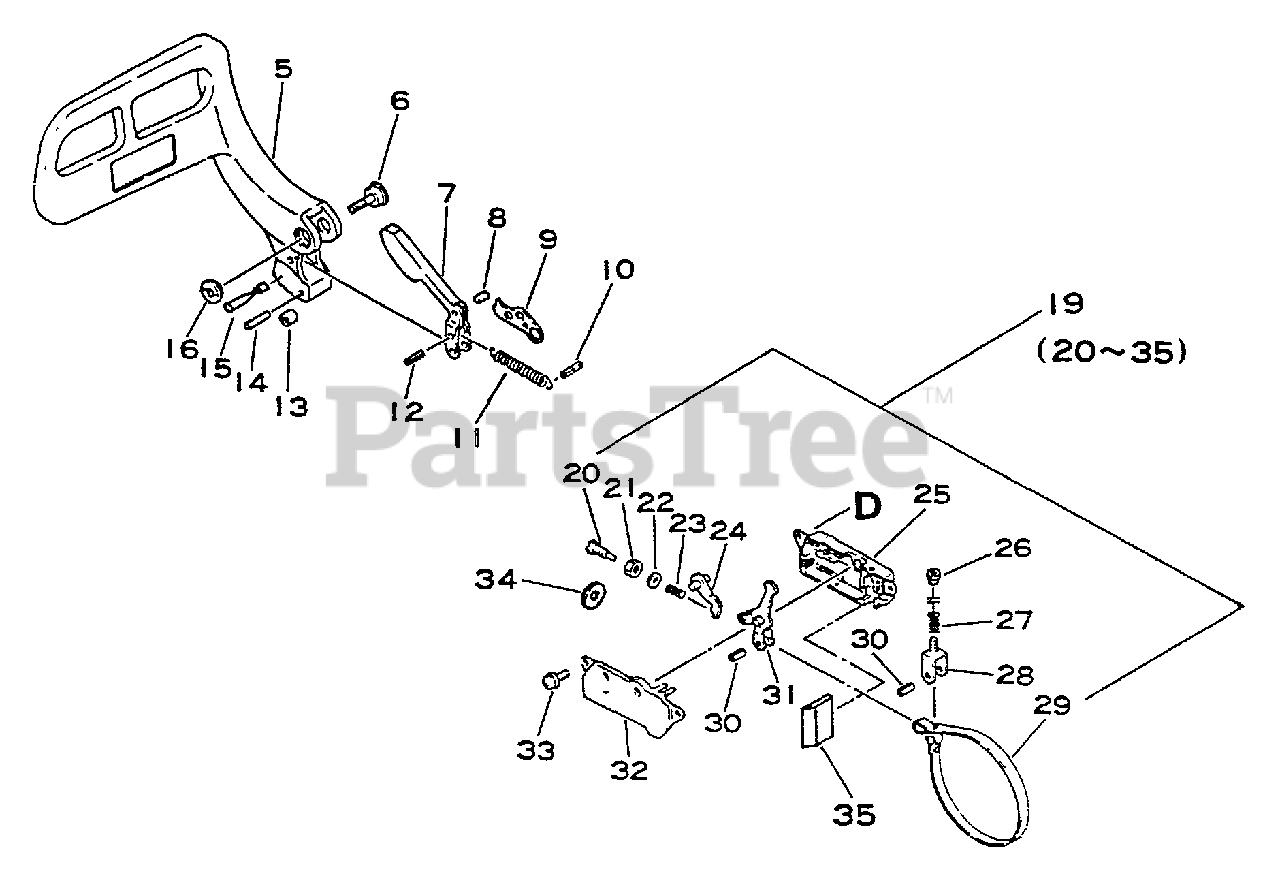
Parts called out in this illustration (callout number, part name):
5	LEVER, BRAKE
7	WEIGHT, BRAKE
8	PIN, LOCATING 4×8
9	STOPPER
10	PIN, SPRING 3×20
11	SPRING, RETURN
12	PIN, SPRING 3×12
13	SPACER
14	PIN, LOCATING 4×8
15	PIN 3×24
19	CHAIN BRAKE ASSY
23	SPRING ,BRAKE
24	STOPPER, BRAKE
25	COVER, BRAKE
28	ADJUSTER, BRAKE BAND
29	BAND, BRAKE
30	PIN, SPRING 4×10
31	LEVER, BRAKE
33	SCREW - 4×10
35	SEAL, DUST
